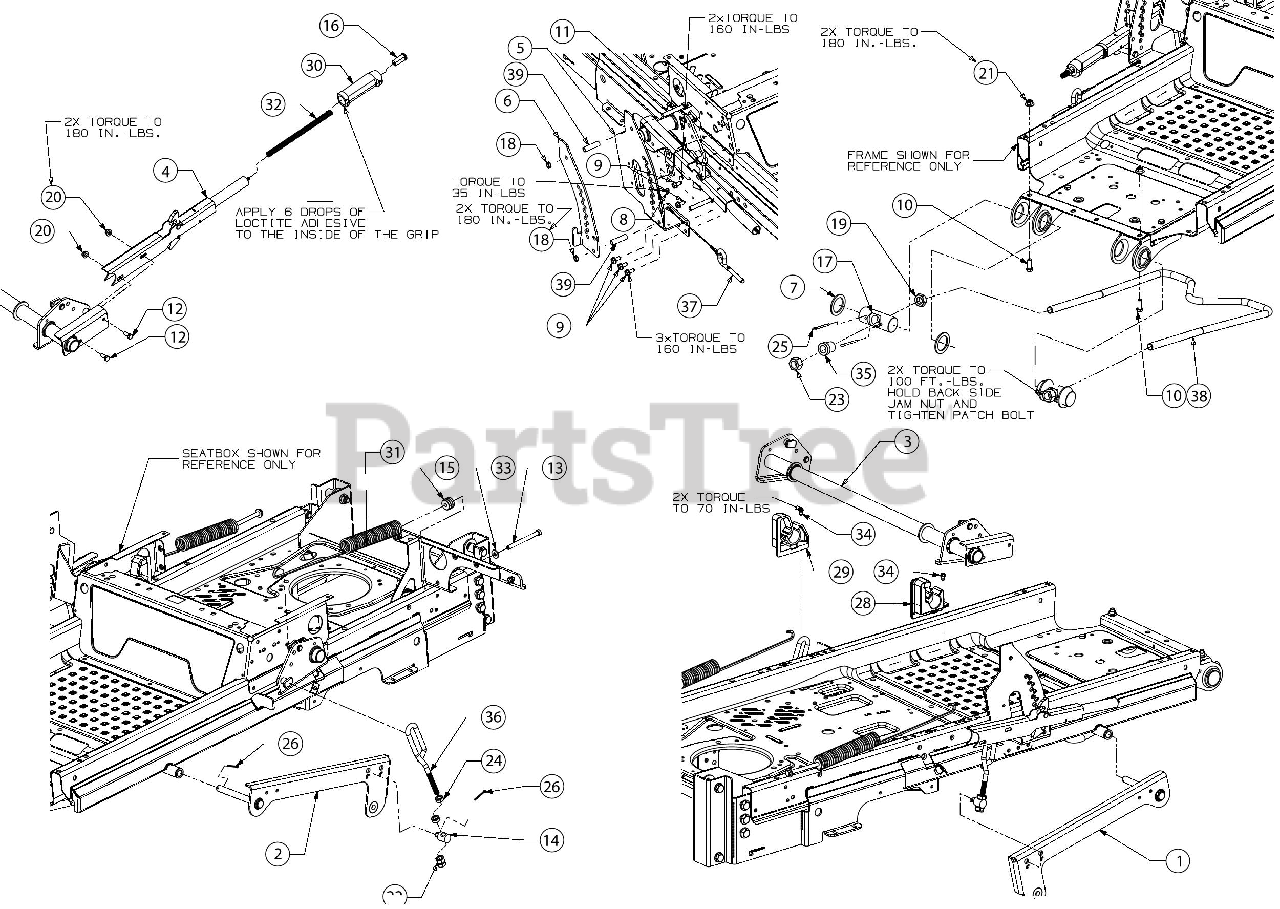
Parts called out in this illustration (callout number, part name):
4	LATCH HANDLE ASSEMBLY
7	FLAT SPACER
8	HEX SCREW AB-TAP #10-16 x 0.500
9	SCREW 5/16-18 x .750
10	SCREW 3/8-16 x 1 GR5
11	HEX SCREW-3/8-16X2.5 GR5
12	SCREW 5/16-18 x .75 GR5
13	SCREW 3/8-16X4.25 GR5
14	LIFT LINK FERRULE
15	SPRING INSERT
16	LIFT HANDLE BUTTON
17	PIVOT LIFT PIN
18	JAM LOCK NUT
19	HEX JAM NUT 3/4-10
20	FLANGE LOCK NUT 5/16-18
21	FLANGE LOCK NUT
22	HEX NUT NYLOK 1/2-13
23	NYLOCK NUT 3/4-10
24	HEX NUT
25	COTTER PIN
26	COTTER PIN
28	DECK LIFT BRACKET
29	DECK LIFT BRACKET (LH)
30	LIFT HANDLE GRIP
31	EXTENSION SPRING 1.485 OD x 17.58
32	COMPRESSION SPRING
33	FLAT WASHER .385X.870X.090
34	SHOULDER SCREW 1/4-20X.50 19"PSH
35	FLANGE BEARING
36	LIFT ADJUSTMENT LINK
38	DECK HANGER ROD
